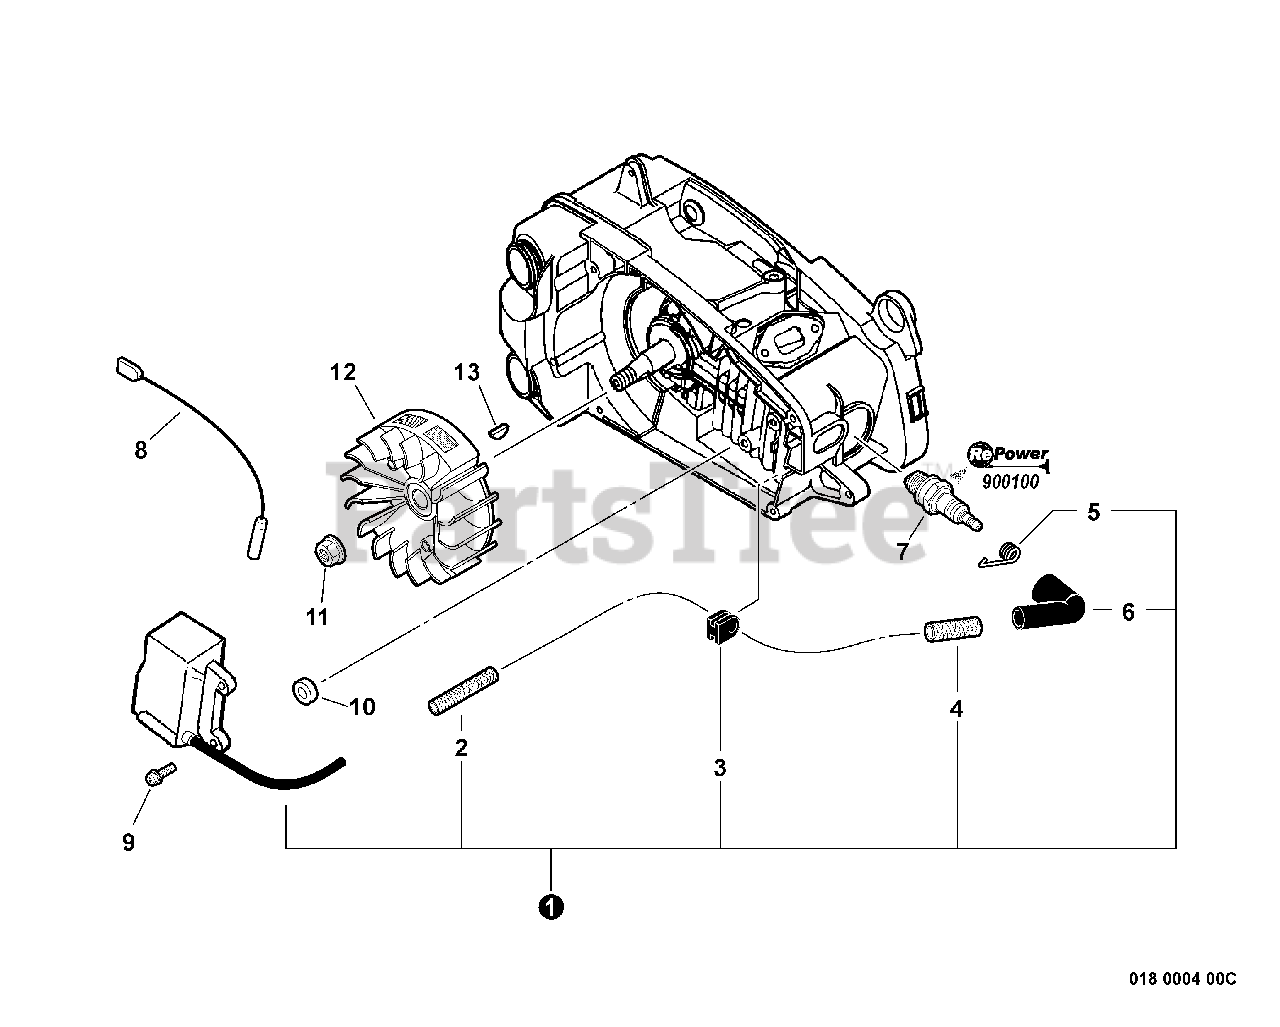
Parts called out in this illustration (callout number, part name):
1	COIL, IGNITION
2	TUBE, INSULATOR
4	TUBE, INSULATOR
5	TERMINAL, SPARK PLUG
6	CAP, SPARK PLUG
7	SPARK PLUG - BPM8Y
7	SPARK PLUG - BPMR8Y
8	LEAD - IGNITION
9	SCREW 5×22
10	WASHER 5.2×12×3
11	NUT, FLANGE M8
12	FLYWHEEL
13	KEY, WOODRUFF
14	REPOWER TUNE-UP KIT
